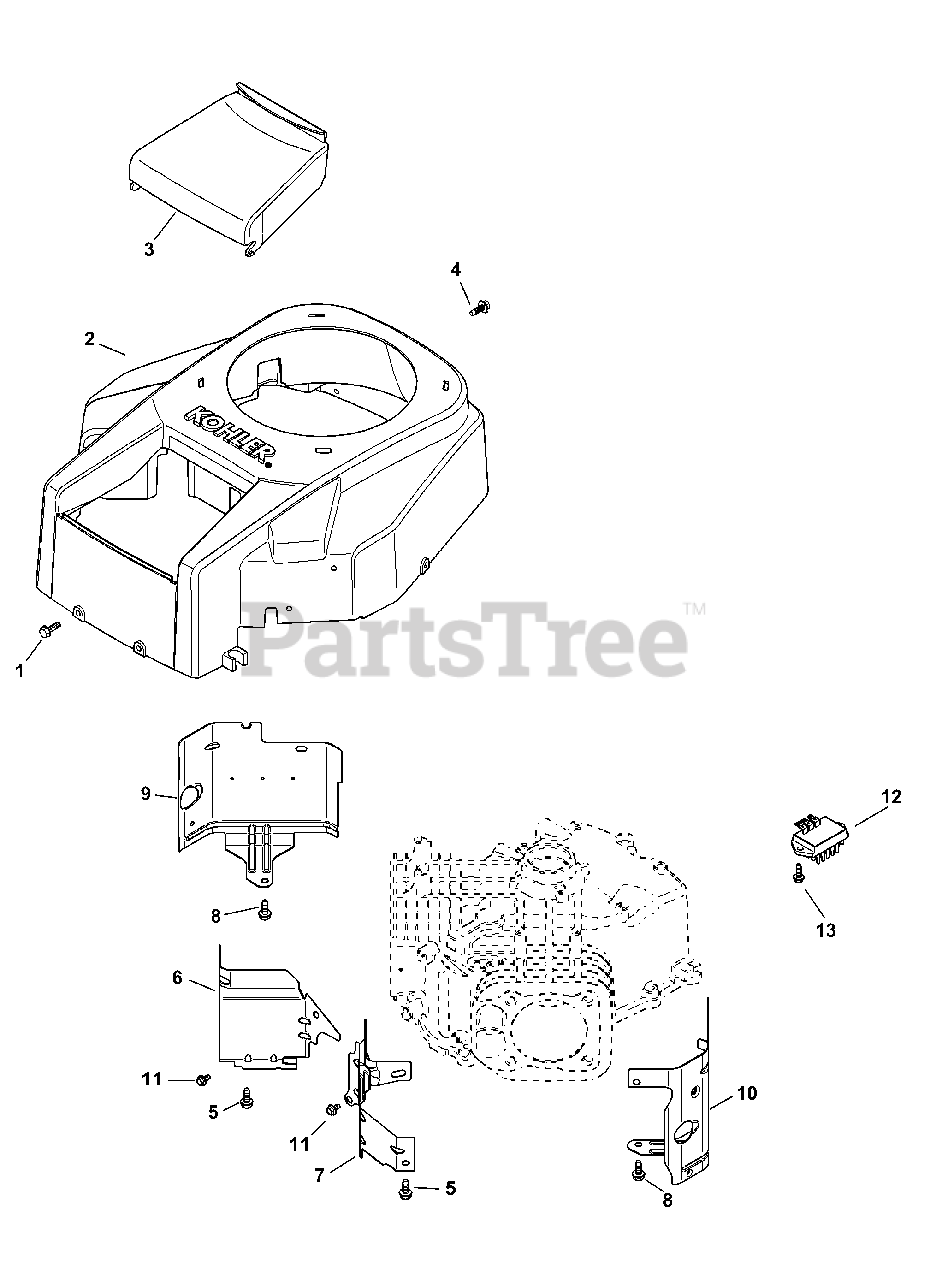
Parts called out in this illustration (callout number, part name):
1	Tap Screw, M6 x 1.7 x 18
2	Housing Blower Kit
3	Air Cleaner Cover
4	Flg. Thd. Frm. Screw, M5 x 0.8 x 16
5	Flg. Thd. Frm. Screw, M6 x 1.0 x 16
6	Valley Baffle - #1 Cylinder
7	Valley Baffle - #2 Cylinder
8	Flng. Thd. Frm. Screw, M6 x 1.0 x 10
9	Cyl Barrel Baffle - #1 Side
10	Cyl Barrel Baffle - #2 Side
11	Flg. Thd. Frm. Screw, M5 x .8 x 10
12	Regulator/Rectifier
13	Flg. Thd. Frm. Screw, M5 x .8 x 20
